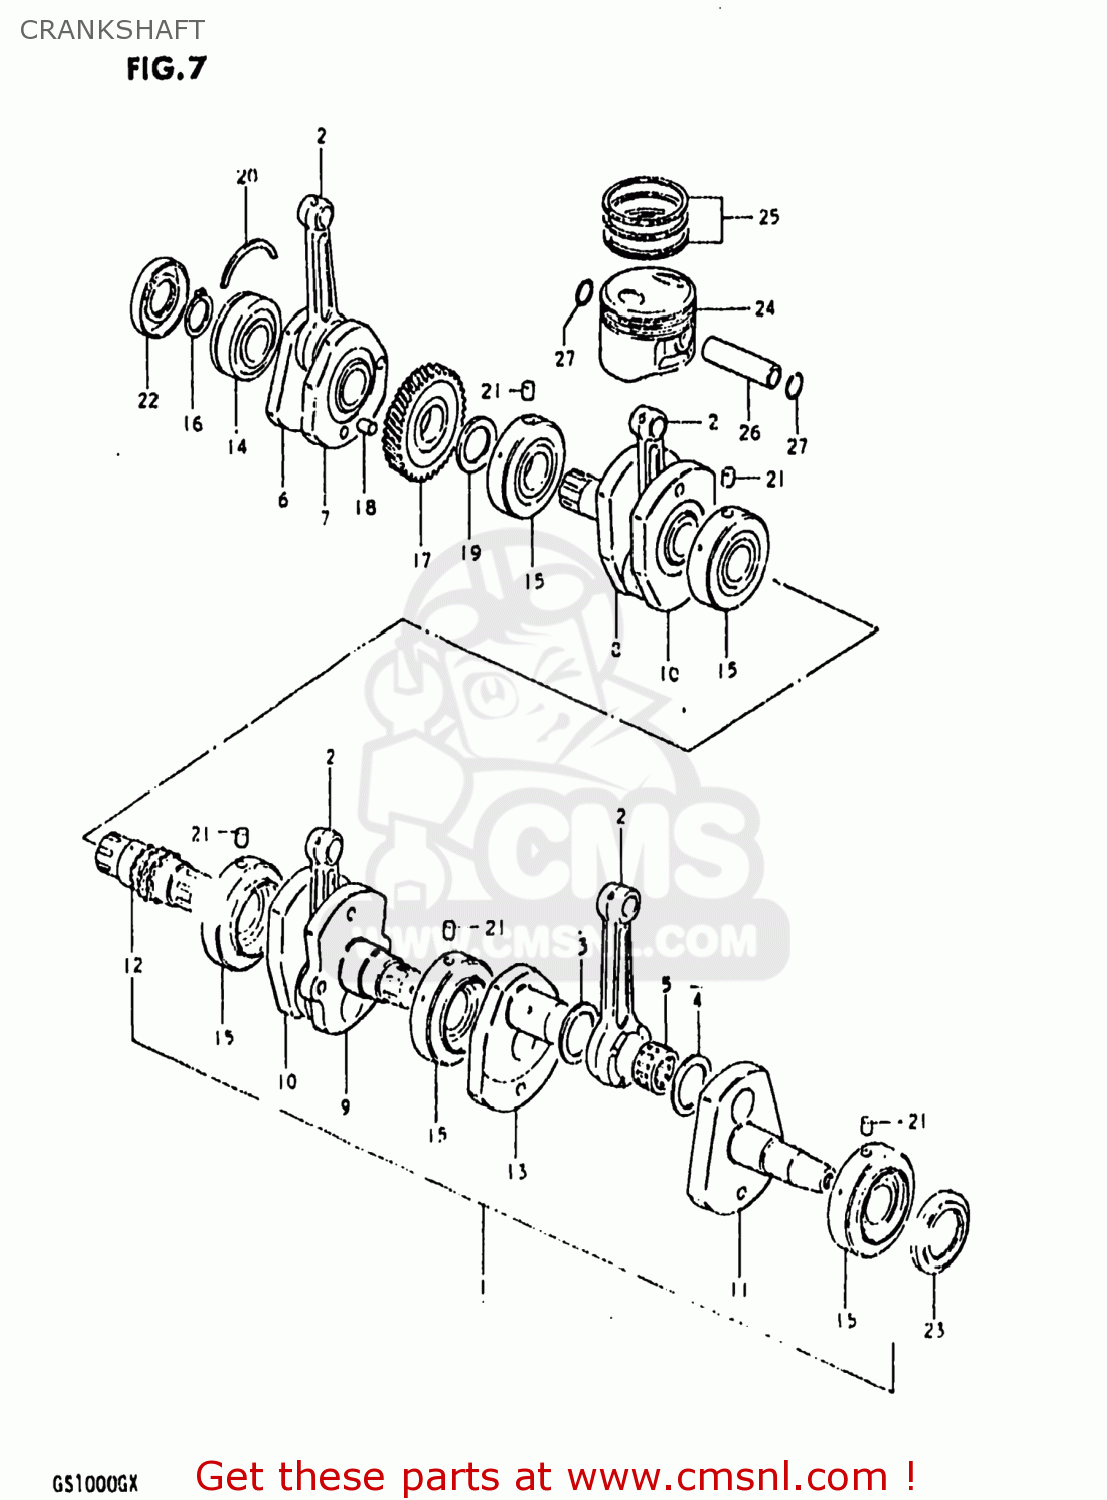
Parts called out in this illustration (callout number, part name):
1	CRANKSHAFT ASSEMBLY
2	ROD,CONNECTING
3	WASHER (29X48X2)
4	WASHER (29X48X1)
5	BEARING(29X39X20)
6	CRANKSHAFT
7	CRANKSHAFT
8	CRANKSHAFT
9	CRANKSHAFT
10	WEB,CRANK,MIDDLE
11	CRANKSHAFT,LEFT
12	SHAFT,TIMING CHAIN DRIVE
13	WEB,CRANK
14	BEARING(30X72X19)
15	BEARING
16	CIRCLIP,30MM
17	GEAR,PRIMARY DRIVE
18	PIN
19	WASHER
20	C RING
21	PIN
22	SEAL,OIL(30X72X11)
23	SEAL,OIL(47.3X60X6.5)
24	PISTON
25	RING SET,PISTON
26	PIN,PISTON (18MM)
27	CIRCLIP
